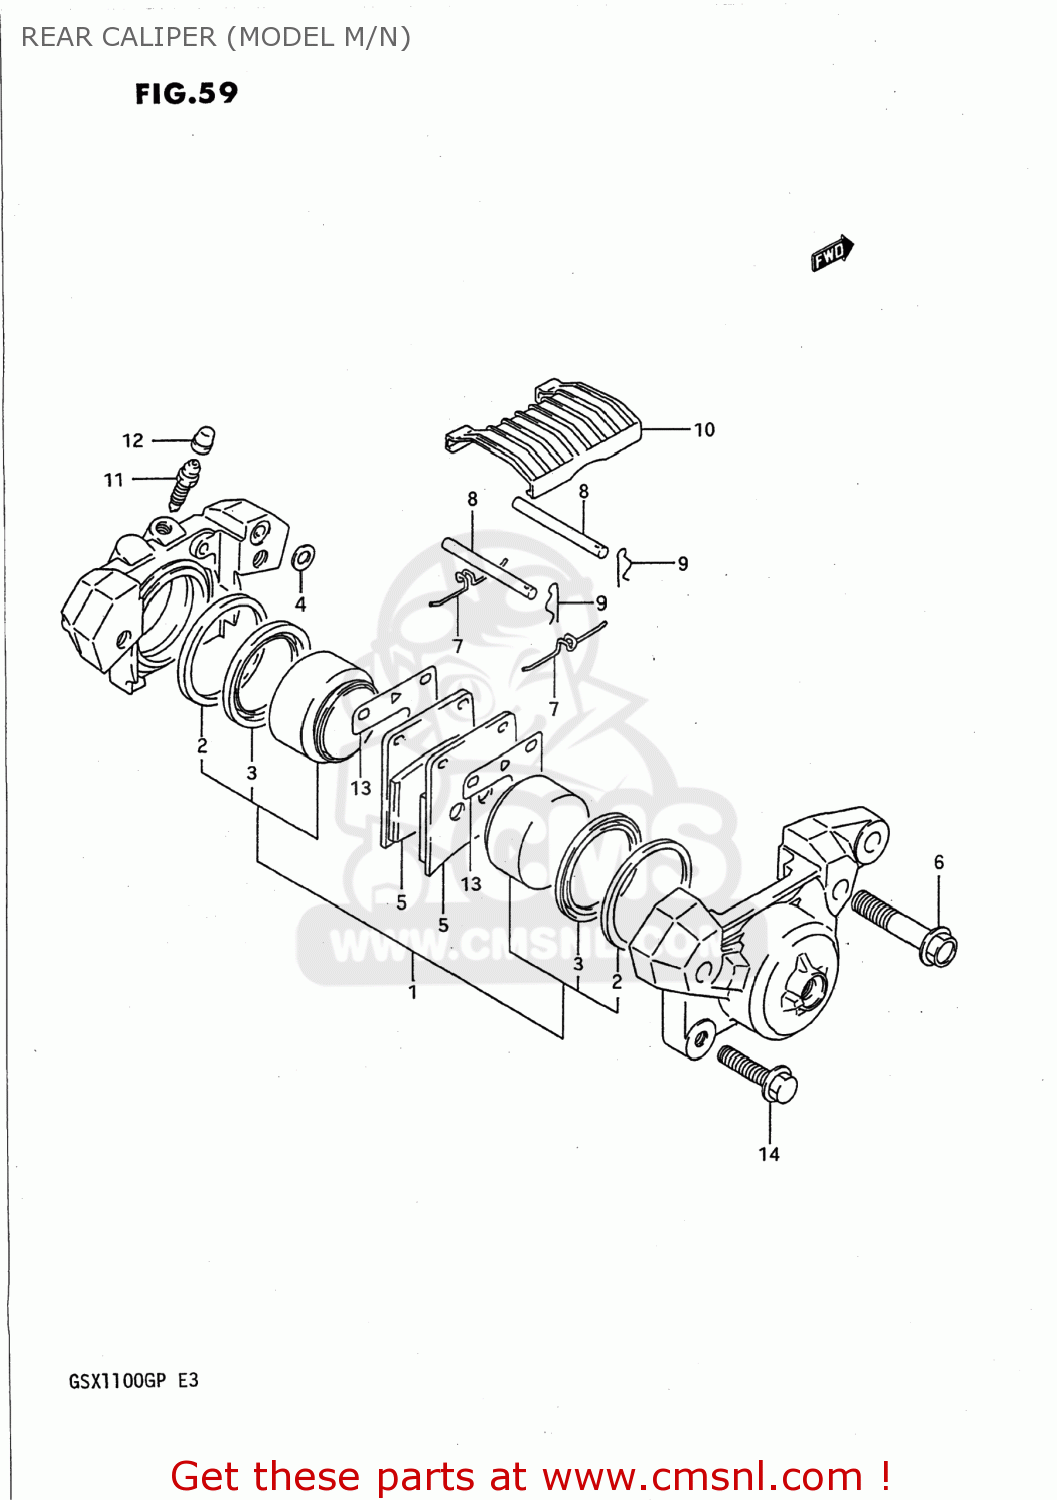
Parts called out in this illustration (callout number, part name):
1	PISTON SET
2	SEAL,FR CALIPE
3	BOOT,PISTON
4	SEAL,JOINT
5	PAD,BRAKE
6	BOLT,HOUSING
7	SPRING
8	PIN,PAD
9	CLIP,PAD PIN
10	COVER
11	BLEEDER
12	CAP,BREATHER
13	SHIM,PAD
14	BOLT
